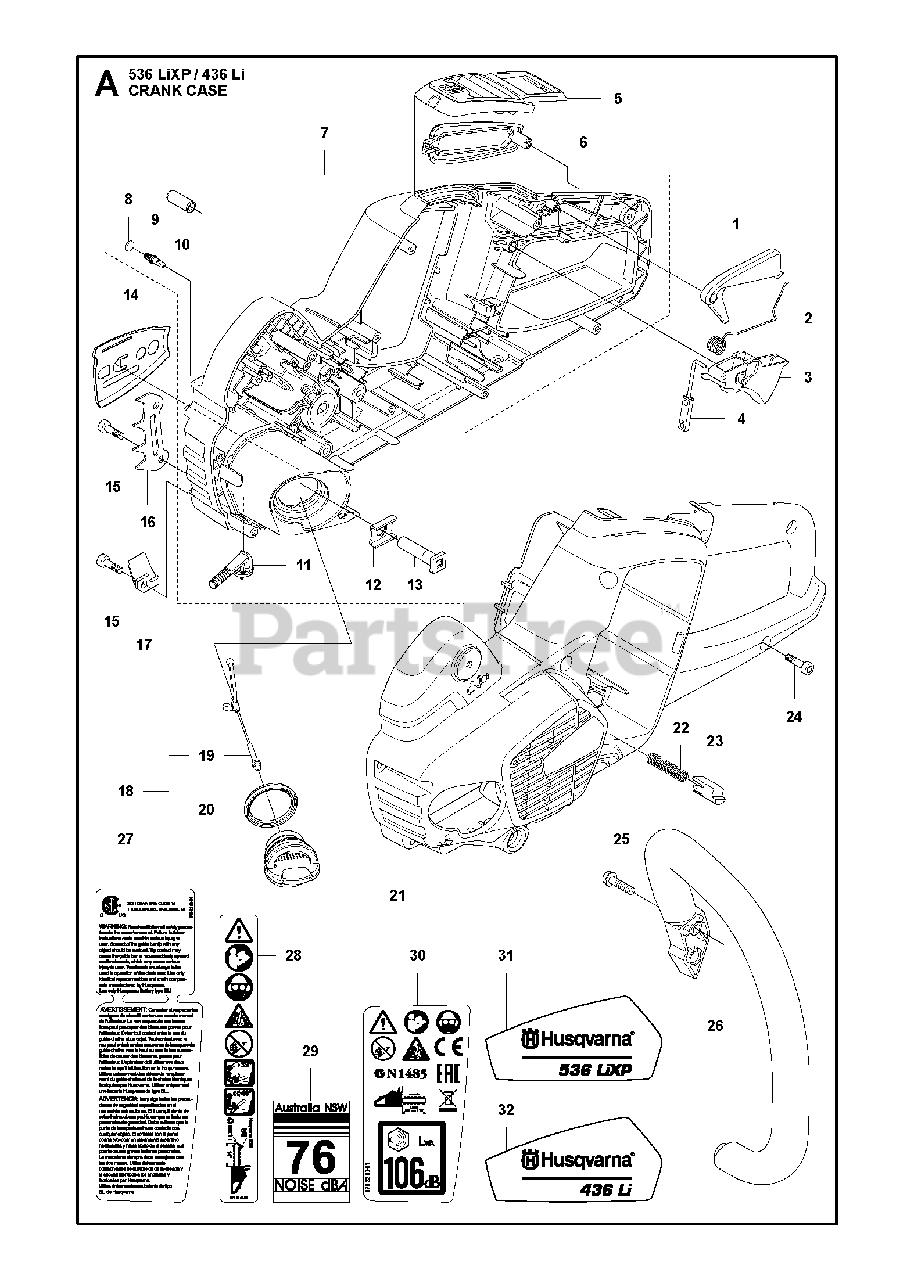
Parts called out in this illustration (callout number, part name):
1	THROTTLE LOCKOUT
3	THROTTLE CONTROL
4	THROTTLE ROD ASSY
6	HANDLE INSERT
7	CRANKCASE ASSY
8	PLUG
9	VALVE-CHECK (DUCKBILL)
10	GUIDE BAR LOCATING PIN
12	PLATE
13	BOLT
14	CHAIN GUIDE
16	INDRE BARKSTØD
17	CHAIN CATCHER
18	TANK CAP ASSY
19	TANK LOCK
20	SEALING
21	CRANKCASE
22	SPRING
23	PUSH BUTTON
24	SCREW IHSCT MT4X18 10.9 ZN/FE
26	FRONT HANDLE
29	LABEL AUSTRAILIA 76 DB
